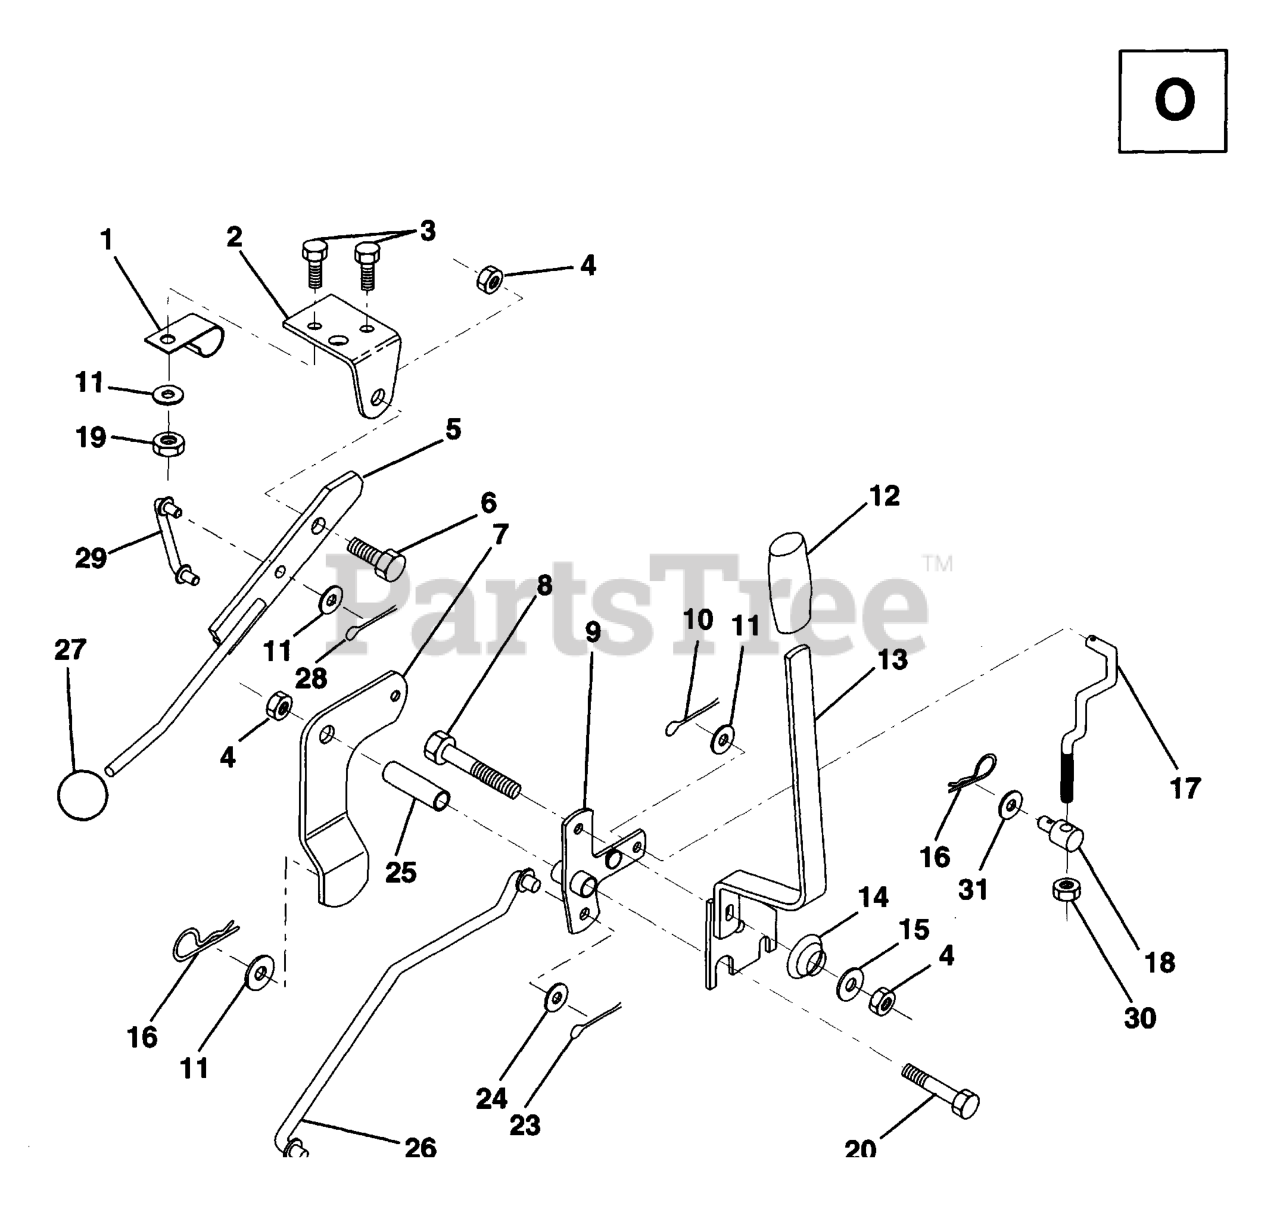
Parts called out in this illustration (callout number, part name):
1	CLIP,INSULATOR
2	BRKT CLUTCH
3	BOLT
5	CLUTCH LEVER
6	BOLT, SHOULDER LT
7	ASSEMBLY MOWER CLUTCH ARM
9	BELLCRANK,LIFT
10	COTTER PIN
11	WASHER
12	HANDLE GRIP
12	GRIP HANDLE
13	LIFT HANDLE ASSY
14	SPRING COMPRESSIO
15	WASHER T
16	SPRING TI
17	LINK LIFT FRT
18	TRUNNION.ADJUSTABLE.3/8-16
19	NUT.CROWNLOCK.1/4
23	PIN COTTER
24	WASHER GT
25	TUBE SPACER
27	KNOB T (3/8 HOLE)
28	COTTER PIN
29	LINK MOWER CLUTCH
30	NUT
31	WASHER
